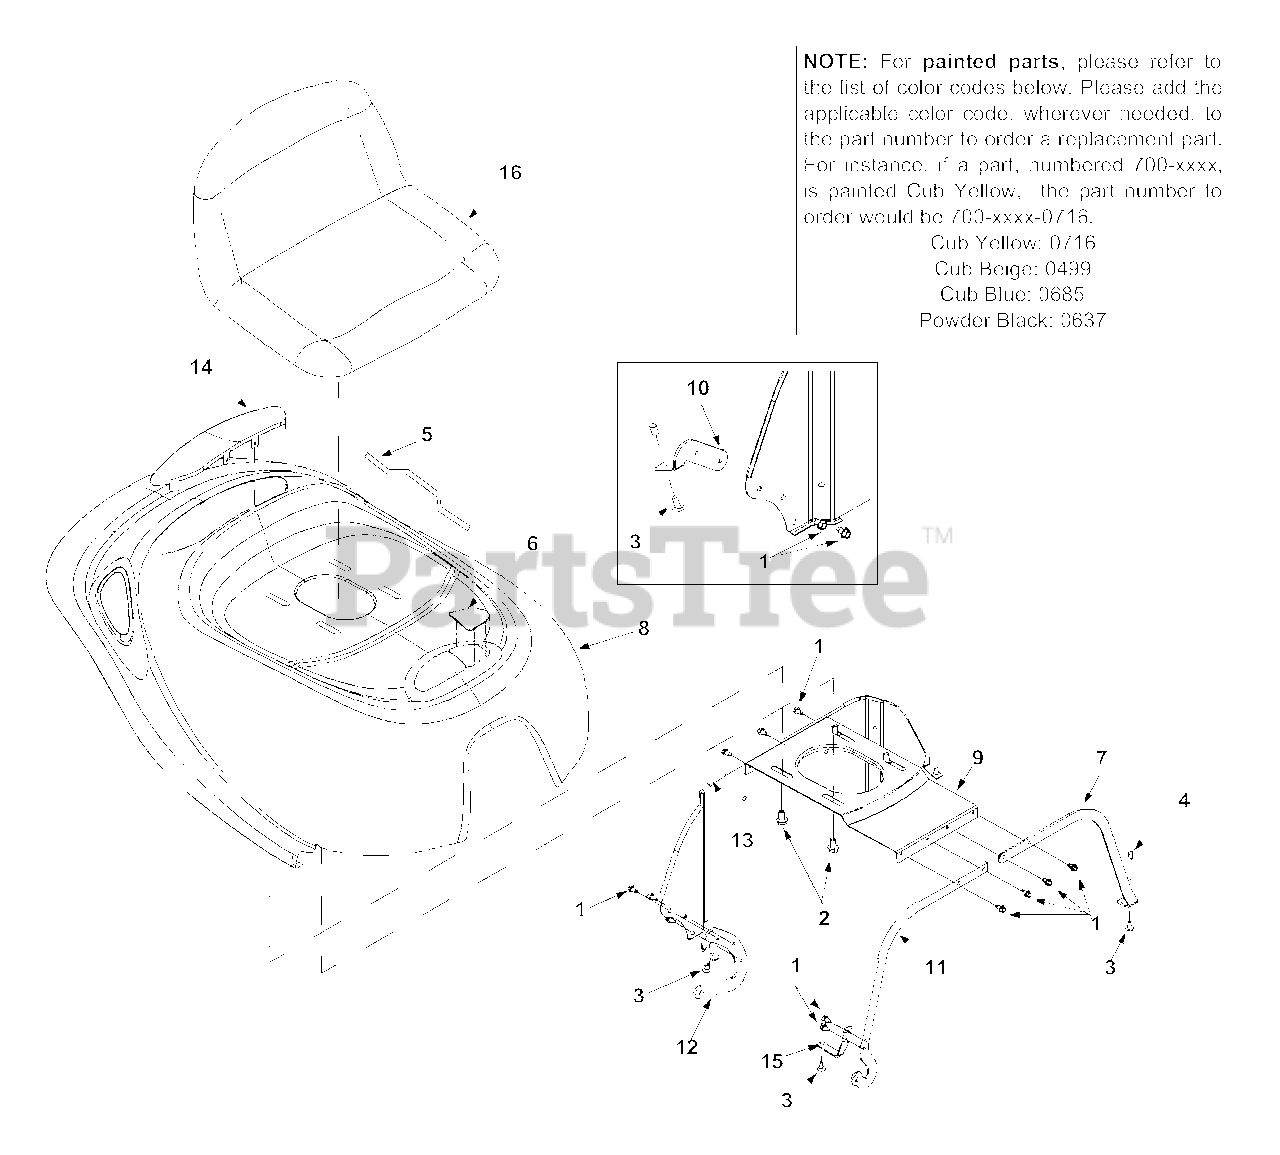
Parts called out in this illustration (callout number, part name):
1	TT Screw 1/4-20 x 0.5
2	TT Screw 3/8-16 x 0.62
3	Torx AB Screw 1/4-14 x 0.625
4	Rod End Grip
5	Trim Strip
6	Grass Bag Lens
7	Bracket Reinforcement: Hood
9	Plate: Hood
10	Hood Bracket
11	Hood Bracket: Reinforcement
16	Seat: Medium, Black
